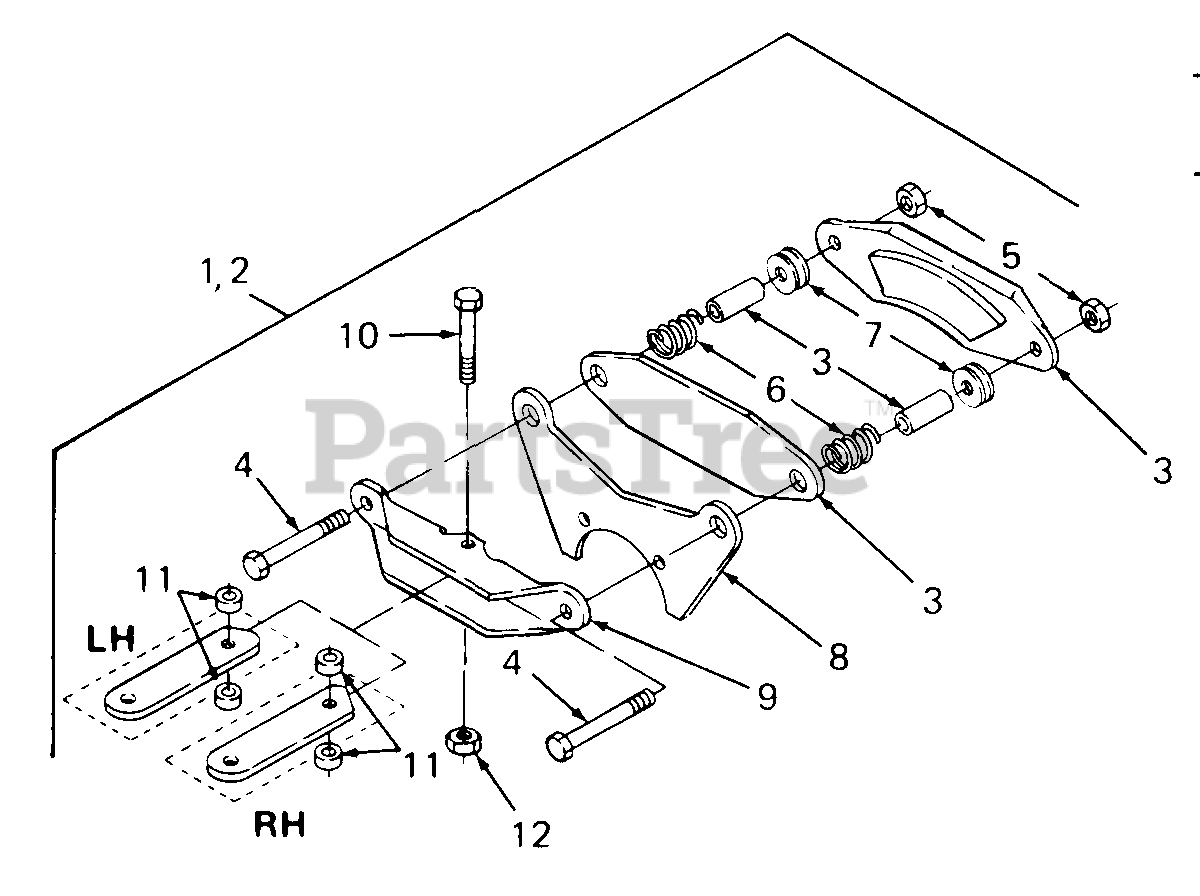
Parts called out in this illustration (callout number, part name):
1	Brake Kit, RH Caliper
2	Brake Kit, LH Caliper
3	Puck Kit, Brake
4	Screw, Hex Cap, 3/8-24 X 2.50 Lg GR5
5	Nut, Hex Lock, 3/8-24 GR5
6	Spring, Compression
7	Washer, Flat, .390 X 1.0 X .030 Thk HDN
8	Bracket, Brake Mounting
9	Bracket Assy, Actuator
10	Screw, Shoulder
12	Nut, Hex Top Lock, 1/4-20
